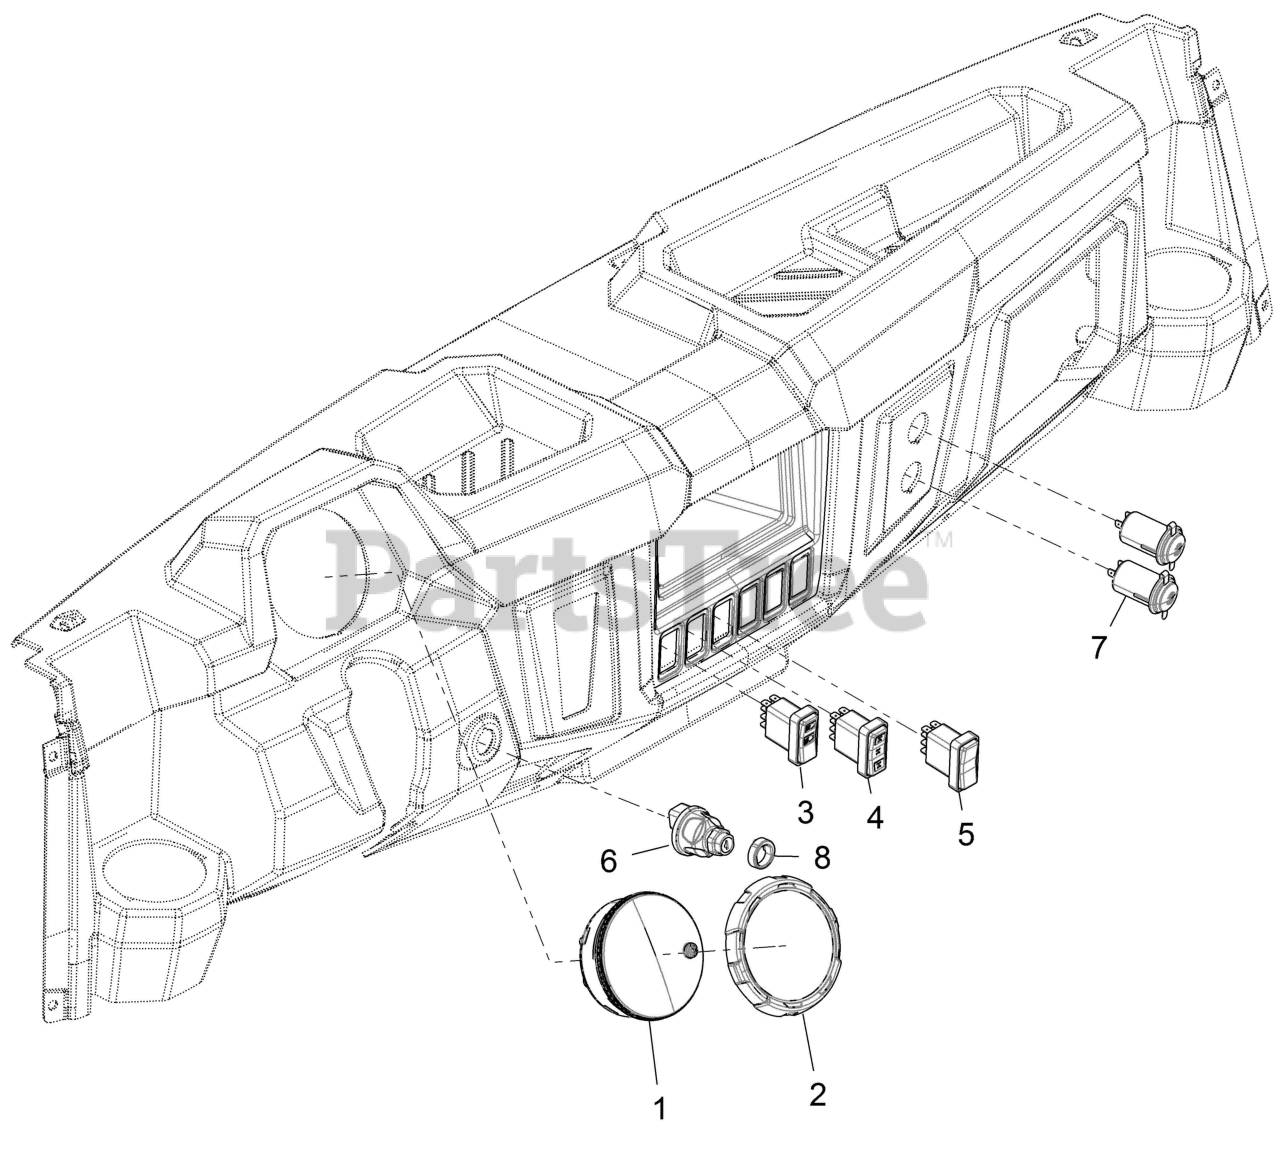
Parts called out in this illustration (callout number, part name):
1	ASM-CLUSTER,CPIA3,OSPS,MD
1	MOUNT-RUBBER,INSTR. CLUSTER
2	BEZEL-INSTRUMENT CLUSTER
3	SWITCH-HEADLIGHT
4	SWITCH-AWD
5	SWITCH-BOX LIFT,MOMENTARY
6	SWITCH,KEY,ARIENS
7	RECEPTACLE-POD MNT,12 VOLT
8	SPACER, KEY, SWITCH
